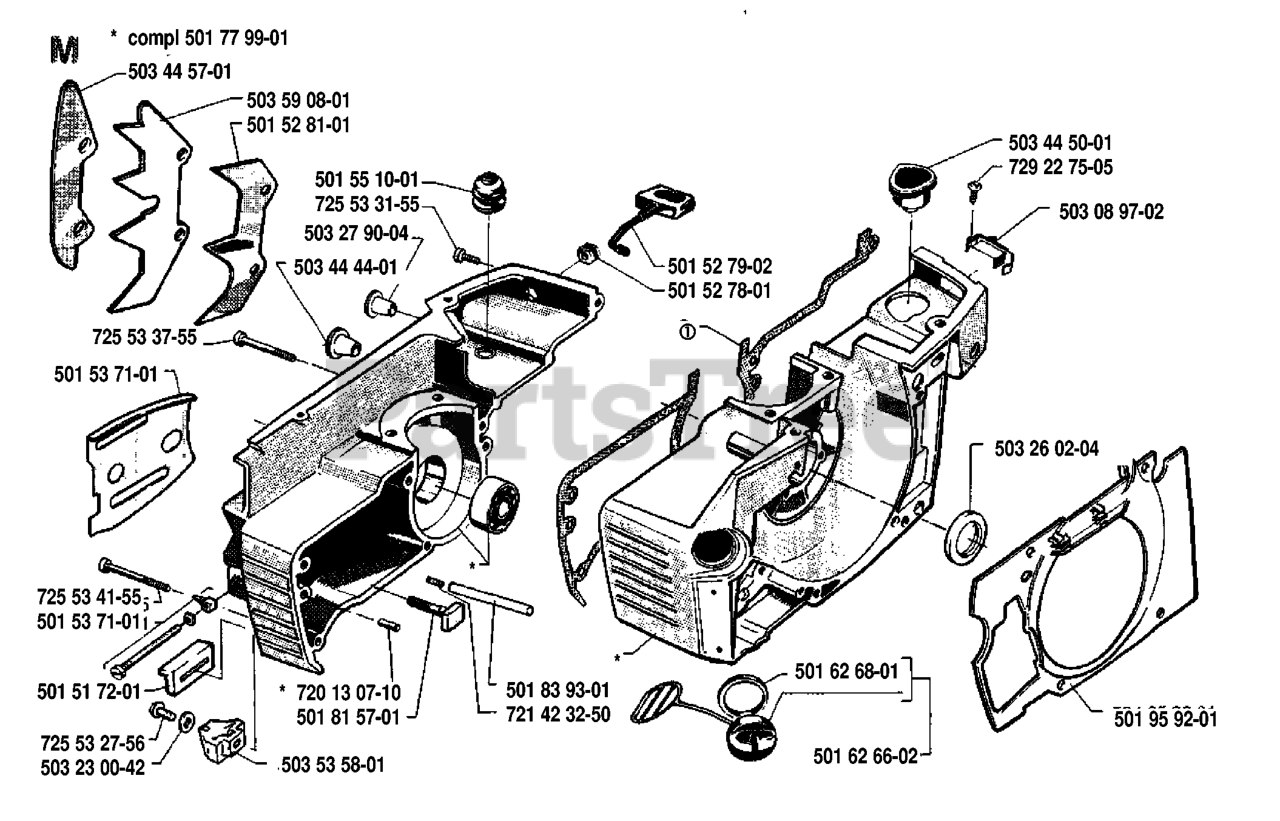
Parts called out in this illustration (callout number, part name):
1	THROTTLE CABLE
2	SCREW.#10 X 0.750.BOS
4	MUFFLER.TWIN.CYL.LOW.TONE
5	RP.EXHAUST.TUBE.LH.BS/TWIN
6	EXHAUST.TUBE.RH.BS/TWIN
8	BOLT.5/16-18UNCX3/4 W/SEMS.BLK
10	SHIELD.HEAT.MUFFLER
13	GASKET.MUFFLER
14	TUBE, DRAIN OIL ASM.
17	SCREW.3/8-16
23	SHIELD.BROWNING.DBR.GUARD
25	CONTROL.CHOKE.ERGO.PUSH-IN.BLA
29	KIT.SPARK ARRESTOR 794945 B&S
31	TANK.ASM.FUEL.FR.2.5GA.
32	CAP ASM.FUEL.2.25"FR.
33	HOSE CLAMP
37	LINE.FUEL.20
38	VALUE.OIL.DRAIN
44	SCREW HEXWSHR 1/4-20X3/4
45	SCREW, 3/8-16X3/4
72	SCREW.SOCKET.HEAD.5/16-18
81	NUT
91	BUSHING.1.375OD
